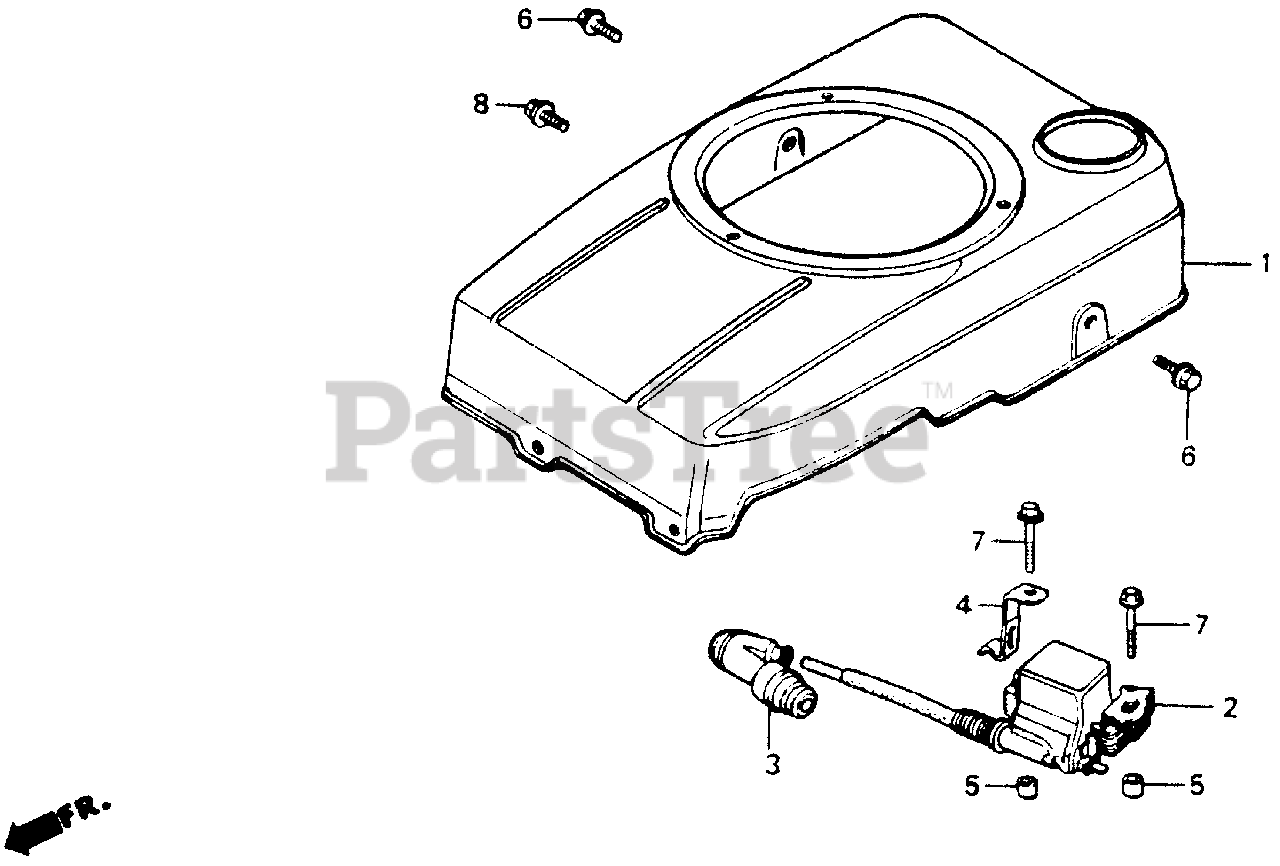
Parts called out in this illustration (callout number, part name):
1	COVER, FAN *R8* (BRIGHT RED)
1	COVER, FAN *R280* (POWER RED)
2	COIL ASSY., IGNITION
3	CAP ASSY., NOISE SUPPRESSOR
6	BOLT, FLANGE (6X12) (CT200)
7	BOLT, FLANGE (6X25)
8	BOLT, FLANGE (6X10)
